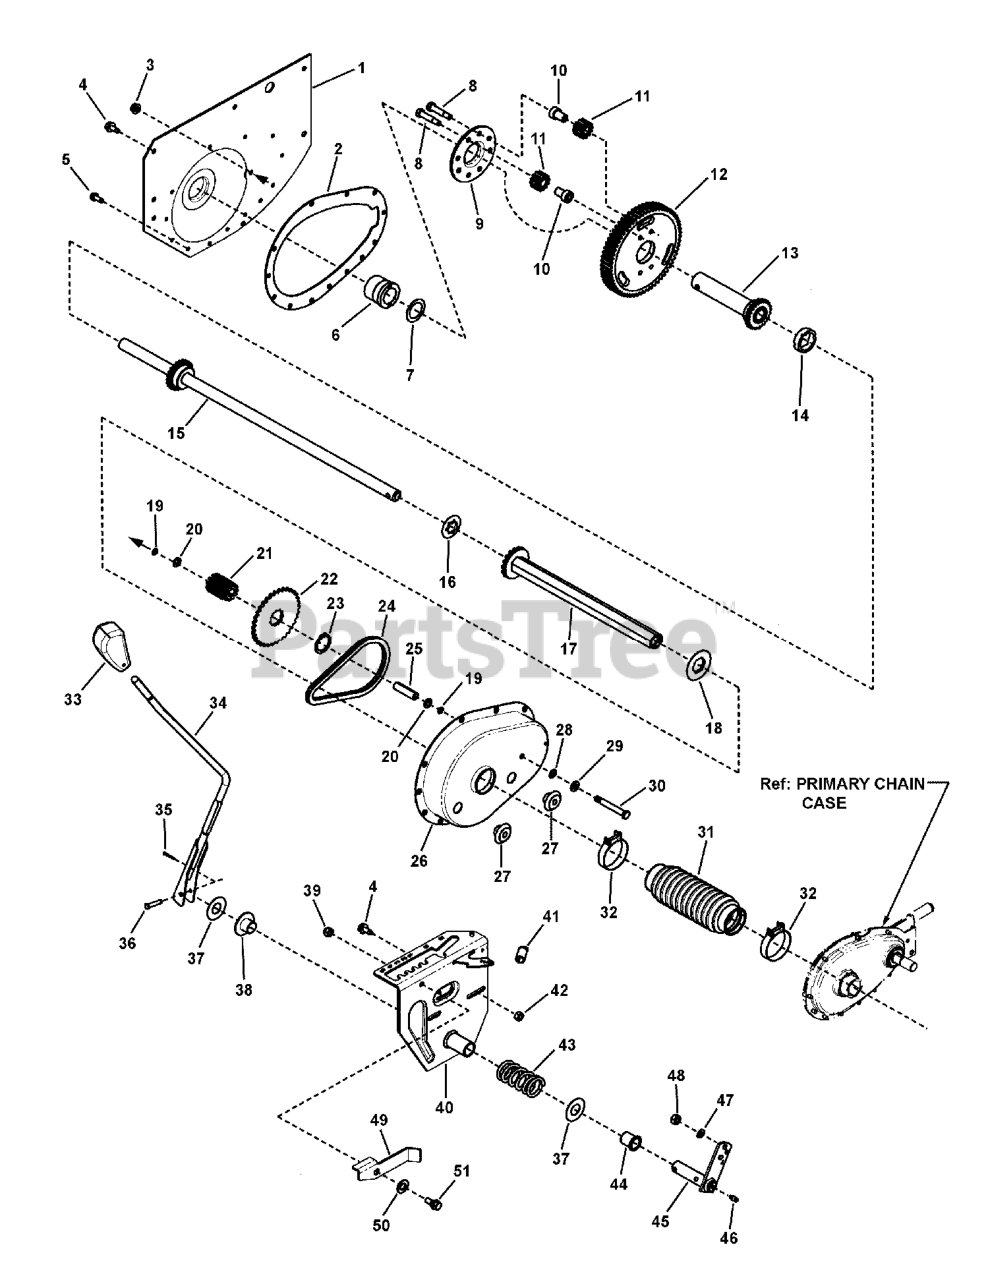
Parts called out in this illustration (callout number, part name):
1	FENDER, Right Hand (1.62" Dia. Hole)
2	GASKET, Transmission Case
3	NUT, 5/16-24 Flange Lock (Large)
4	SCREW, 5/16-18 x 5/8" Hex Washer Self-Tap
5	SCREW, 1/4-20 x 5/8" Hex Washer Head Self-Tap
6	BEARING, Axle (R. H. Fender)
7	WASHER, Thrust
8	BOLT, 5/16-24 x 1-5/8" Hex Special Lock (Vibresist)
9	PLATE, Differential
10	SPACER, Pinion
11	GEAR, Differential Pinion (12T 12P)
12	GEAR, 63 Tooth 10 Pitch (4 Hole)
13	KIT, Short Axle Assembly, 23T (Includes Gear)
14	SPACER, Differential (1.25" ID x .423 Wide)
15	KIT, Long Axle (Includes welded Gear and item #14)
16	WASHER, Thrust
17	ASSEMBLY, Drive Hex Tube
18	WASHER, Nylon
19	O-RING, 5/16"
20	WASHER, 5/16" Belleville
21	GEAR, 11 Tooth, 10 Pitch
22	SPROCKET, 34T, 3/8P
23	RING, 1-3/16" External Retaining
24	CHAIN, 46 Pitch (#35 Endless)
25	SPACER, Differential Case
26	CASE, Transmission
27	PLUG, 1/2" Cup Insert
28	WASHER, 5/16" External Tooth Lock
29	WASHER, .34 x .69 x .08 Flat
30	SCREW, 5/16-24 x 2-5/8" Hex Head Cap
31	BOOT, Oil Seal (Short Axle)
32	BOOT CLAMP, 2"
33	GRIP, Shift Handle
34	WELDMENT, Shift Handle
35	PIN, 3/32 x 3/4" Cotter
36	PIN, 1/4 x 1-3/4" Tapered Clevis
37	WASHER, Thrust
38	BUSHING, 3/4 x 1.62 Flange (Nylon)
39	NUT, 5/16-18 Hex Nyloc
40	KIT, Speed Adjustment Latch Assembly
40-1	RIVET, Shoulder
40-2	DETENT, Shift, Weldment
40-3	STOP, Reverse
41	SPRING
42	NUT, 5/16-18 Hex, GR 5 or B
43	SPRING, Shift Detent
44	BUSHING, 3/4 x I.O. Flange (Nylon)
45	WELDMENT, Arm, Shift Handle (w/grease ftg. Hole)
46	LUBE FITTING, 3/16" Press-In
47	WASHER, .32 x .58 x .08 Split Lock
48	NUT, 5/16-24 Hex, GR 5
49	LEVER, Over-Ride
50	WASHER, .47 x .92 x .065 Flat
51	SHOULDER BOLT, 5/16-18
